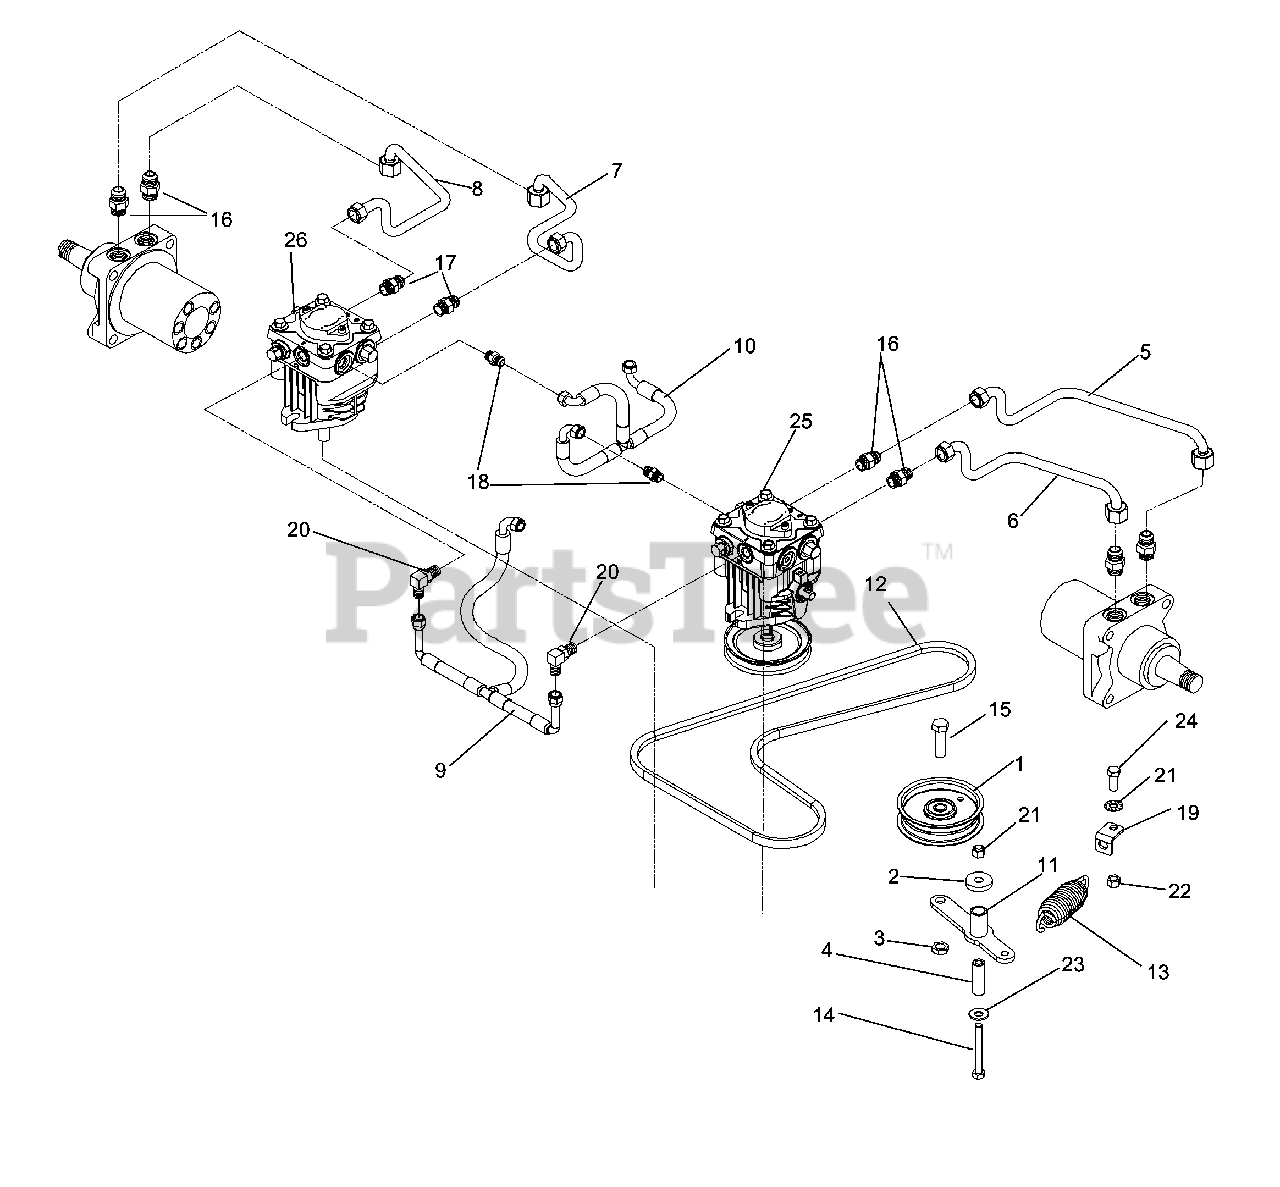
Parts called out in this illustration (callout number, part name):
1	PULLEY IDLER
2	WASHER .43X1.38X.25
3	NUT 1/2-13 HEX JM NYL
4	BUSHING 1.90
5	TUBE HYD. LH-A
6	TUBE HYD. LH-B
7	TUBE HYD. RH-A
8	TUBE HYD. RH-B
9	T-ASM HYD. SUCTION
10	T-ASM HYD. CASE DRAIN
11	WLDT BELT TENSIONER
14	3/8-16 X 3` HHB
15	1/2-13X1-3/4 HHB GR. 5
16	FITTING HYDRAULIC
17	FITTING HYDRAULIC
18	FITTING HYDRAULIC
19	SPRING BRKT.
20	ADAPTER-MALE 9/16-18
21	3/8 INT/EXT.L-WASHER
22	NUT 3/8-16 NYLOC
23	WASHER 3/8 FLAT
24	HCS 3/8C X 1
25	PUMP PARKER H110 LH
26	PUMP PARKER H110 RH
